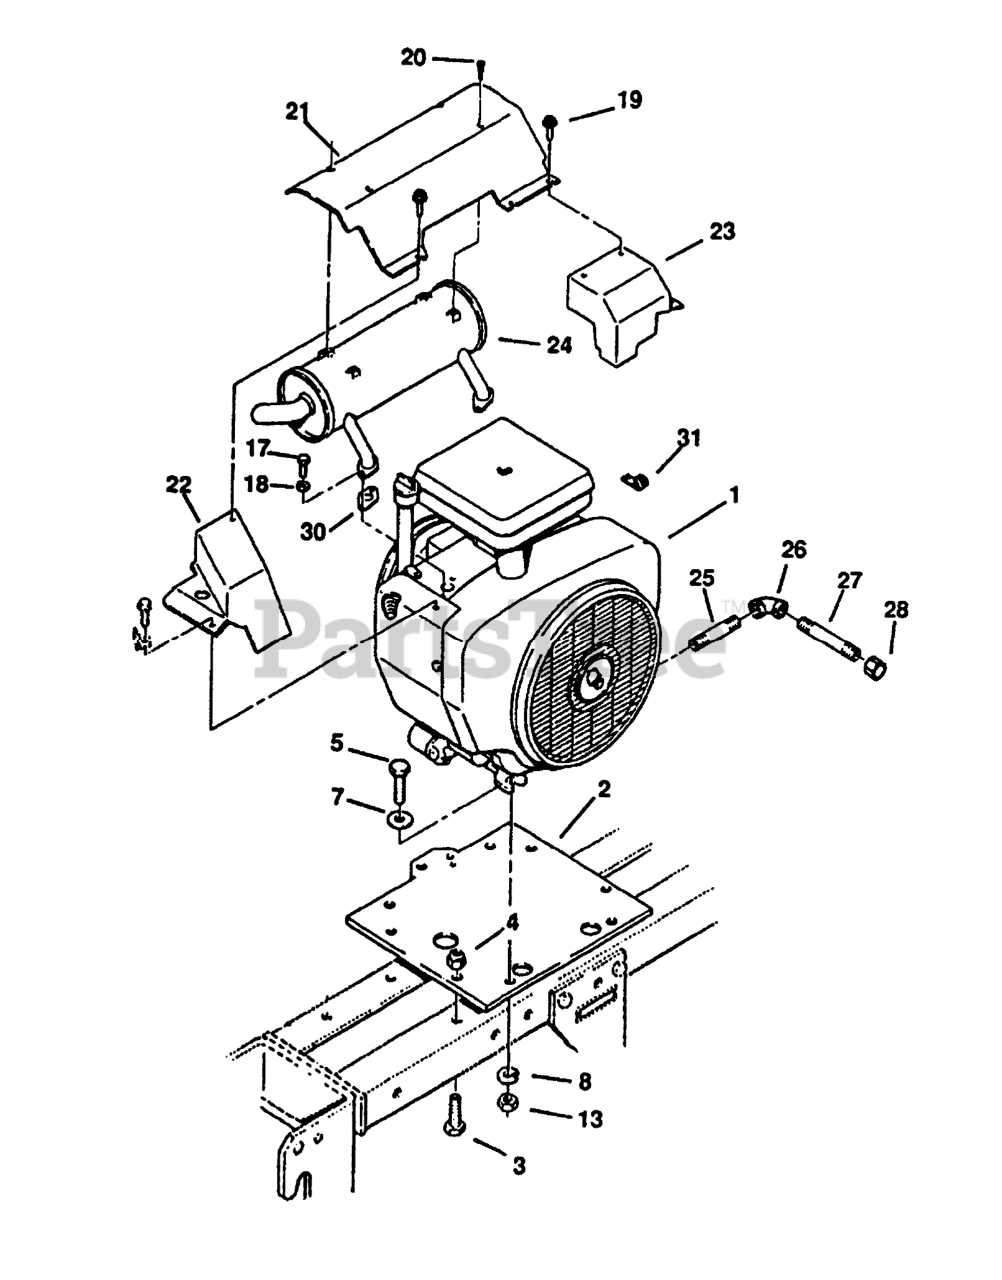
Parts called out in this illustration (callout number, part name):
1	Engine-16HP TORO Power Plus P216G-I/10976D
2	PLATE-ENGINE B
3	Bolt
5	Bolt
7	WASHER-FLAT
8	WASHER-LOCK/SP
13	NUT-HEX
17	SCREW-HH
18	WASHER-LOCK
19	SCREW-HH
20	Screw
21	Air Deflector
22	LH Exhaust Cover
23	RH Exhaust Cover
24	MUFFLER-EXHAUST
25	Pipe
26	ELBOW 3/8 90 DEG
27	PIPE-NIPPLE 3/8 X 4"
28	Cap
30	Exhaust Gasket
31	J-CLIP
